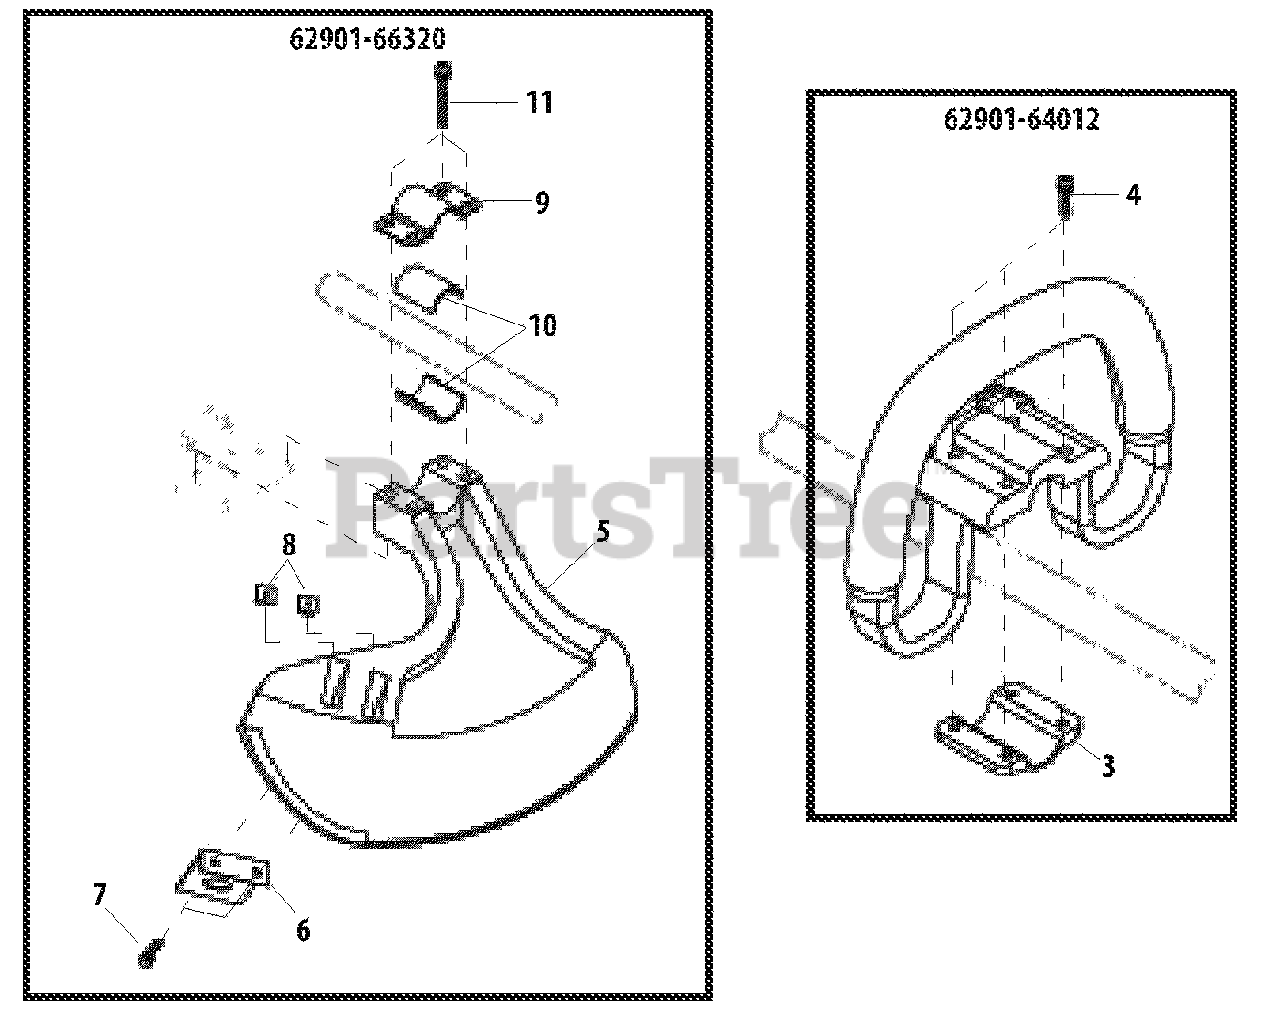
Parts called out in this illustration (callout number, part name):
3	CLAMP - LOWER
4	SCREW - 5X25
5	SHIELD
6	KNIFE, TRIMMER LINE
7	SCREW - 5X16
8	NUT - 5
9	CLAMP - UPPER
10	SPACER
11	SCREW - 5X45
62901-64012	HANDLE ASSY
62901-66320	GUARD ASSY
